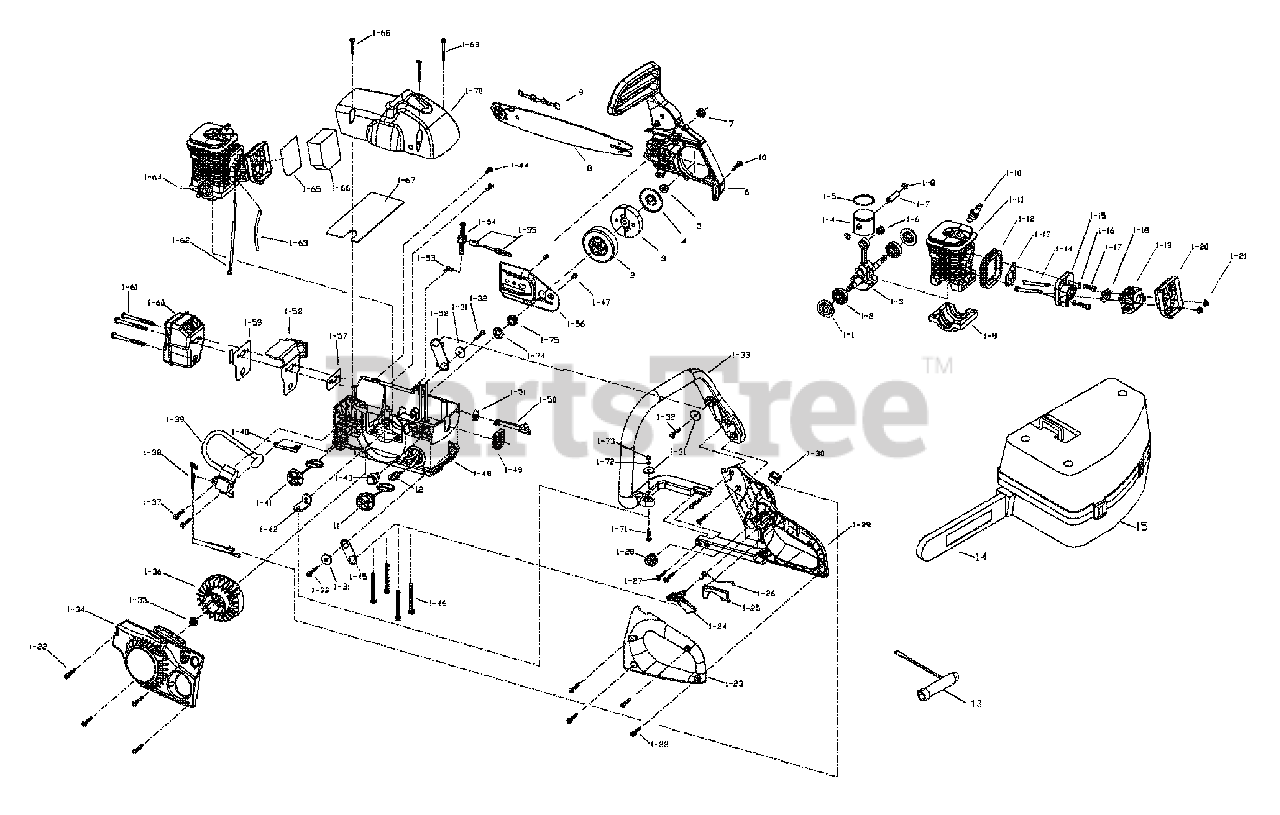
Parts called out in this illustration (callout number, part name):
1	ENG ASS'Y
1-1	CAP, BEARING
1-3	CRANK/ROD ASS'Y
1-5	RING, PISTON
1-6	ROLLER, PISTON
1-7	PIN, PISTON
1-9	CASE, CRANK
1-10	SPARK PLUG
1-12	RUBBER, ISOLATOR
1-16	SPRING WASHER
1-19	CARBURETOR
1-20	AIR FILTER ASS/Y
1-23	HANDLE, LEFT PART
1-24	TRIGGER, THROTTLE
1-25	TRIGGER, RELEASE
1-29	HANDLE, REAR
1-33	HANDLE, FRONT
1-34	STARTER HOUSING ASS'Y
1-38	WIREASS'Y
1-39	IGNITION ASS'Y
1-40	CONDUCTIVE PLATE
1-41	OIL CAP ASS'Y
1-42	FIX PLATE
1-45	FIX PLATE
1-48	HOUSING ASS'Y
1-49	HOLDER, CABLE
1-50	LEVER, CHOKE (MTD BLUE)
1-51	HOLDER, CHOKE LEVEL
1-52	FIX PLATE
1-53	CONNECTOR
1-55	PUMP ASS'Y
1-56	CAP, ANTI-DUST
1-60	MUFFLER ASS'Y
1-62	CABLE, THROTTLE
1-63	FUEL PIPE
1-64	WOODRUFF KEY
1-66	FILTER, AIR
1-72	SPRING WASHER
2	DRUM ASS'Y
3	CLUTCH ASS'Y
4	CAP, ANTI-DUST
6	BRAKE KIT ASS'Y
8	BAR (MS1434NAV/MS1436NAV)
9	CHAIN (MS1434NAV/MS1436NAV)
11	FUEL CAP ASS'Y
14	SCABBARD (MS1636NAVCC)
15	CARRY CASE (MS1636NAVCC)
